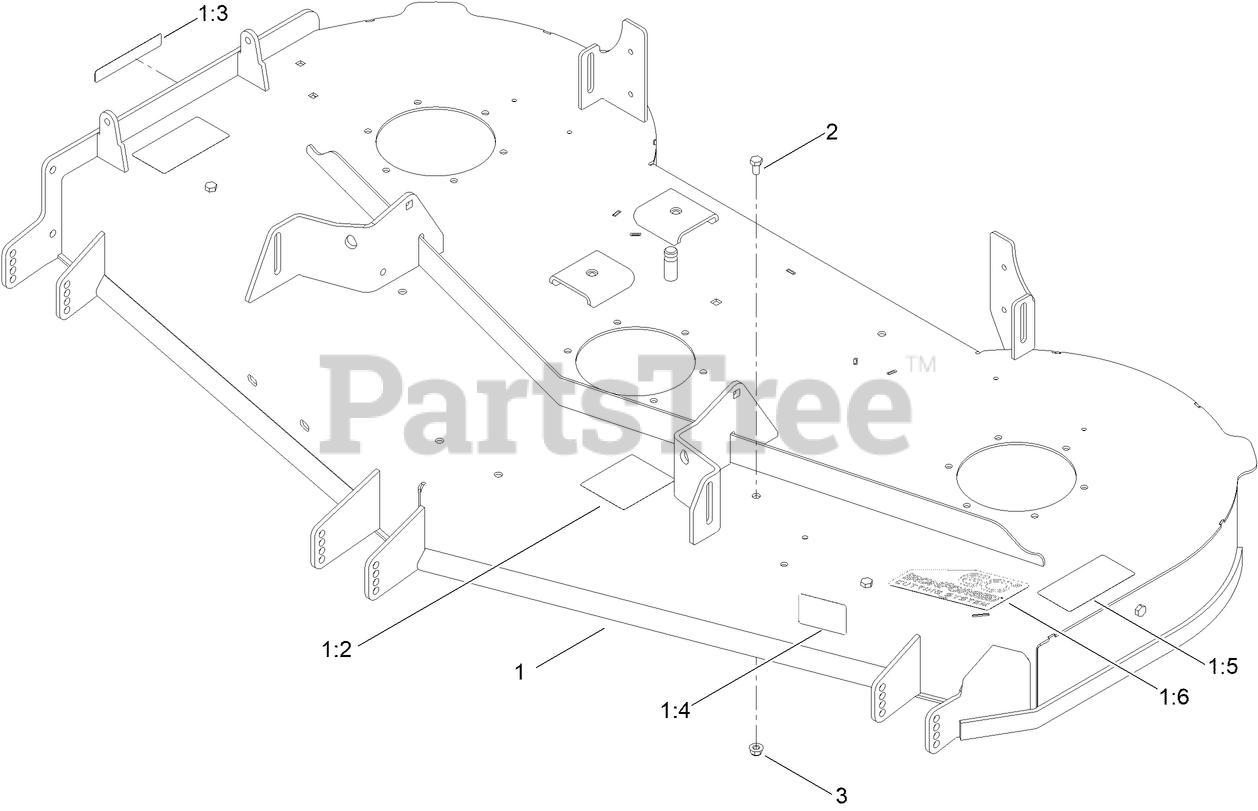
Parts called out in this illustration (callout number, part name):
1:2	DECAL-ROUTING, BELT
1:3	DECAL-DANGER
1:4	DECAL-SCALP, ANTI
1:5	DECAL-DANGER, DECK
1:6	DECAL - DECK
2	SCREW-HH
3	NUT-HF, NI
